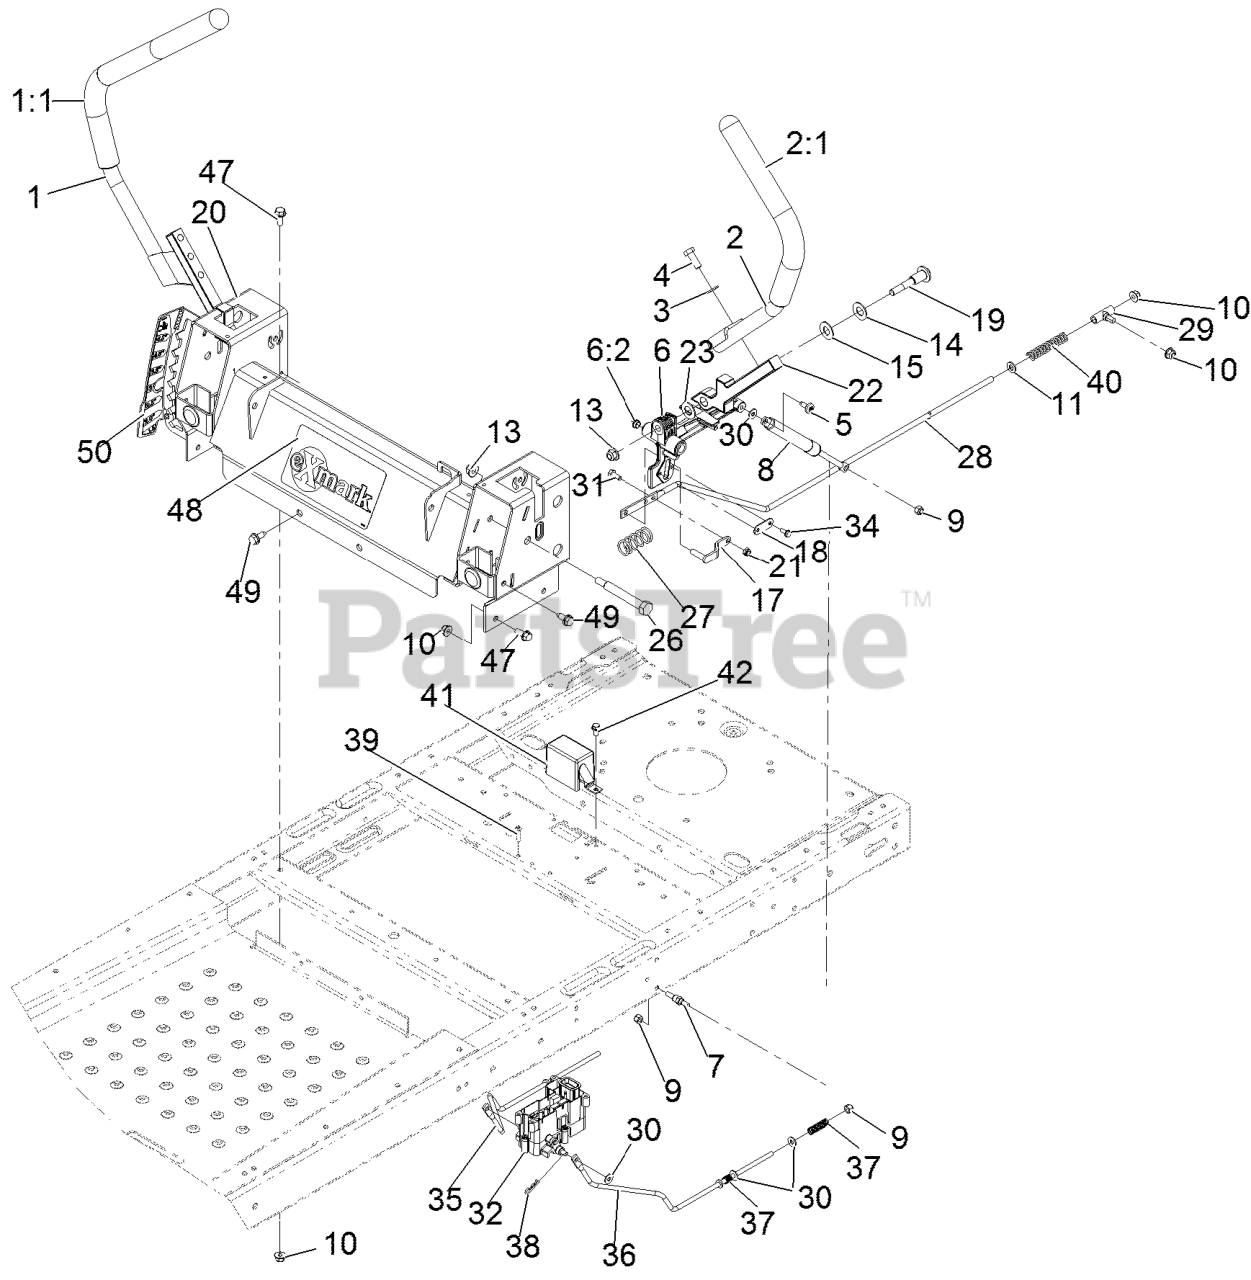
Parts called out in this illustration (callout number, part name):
1	HANDLE-CONTROL, RH
2	HANDLE-CONTROL, LH
3	WASHER-FLAT
4	SCREW-HH
5	SCREW-SHOULDER
6	ACTUATOR ARM ASM
6:2	BUSHING-FLANGE
7	STUD-DAMPER
9	NUT-LOCK, NI
10	NUT-HF, NI
11	WASHER-PLAIN
13	NUT-HF, NI
14	WASHER-BELLEVILLE
18	PLATE-STOP, HYDRO
19	BOLT-PIVOT
20	CONTROL BOX ASM
21	NUT-LOCK, NI
23	WASHER-NYLON
26	BOLT-PIVOT
27	SPRING-RETURN
28	ROD-HYDRO
29	MOUNT-ROD, HYDRO
31	SCREW-HH
34	SCREW-TAPTITE
35	ROD-BRAKE, RH
36	ROD-BRAKE, LH
37	SPRING-COMPRESSION
39	SCREW-PPH
40	SPRING-RETURN, NEUTRAL
41	COVER-BRAKE
42	SCREW-HWH
47	SCREW-HHF
49	Screw-HWH 5/16-18 X 3/4 Tf
50	DECAL-HOC
